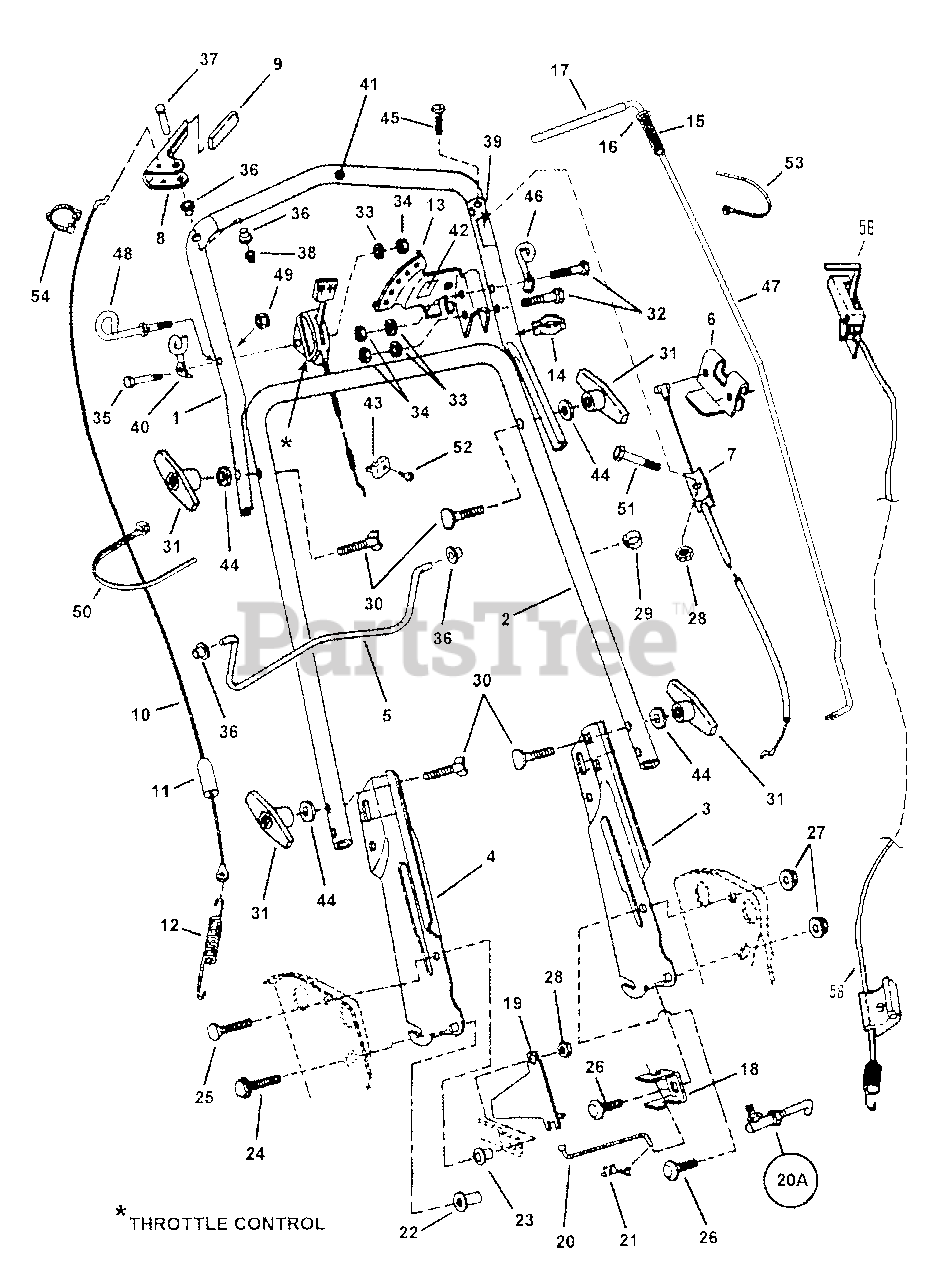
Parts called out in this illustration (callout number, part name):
1	HANDLE, Upper
2	HANDLE, Middle- 1990
3	HANDLE, Lower Left Hand
4	HANDLE, Lower Right Hand
5	BAIL, OPC Control (12.5" Wide)
6	CLIP, Blade Control
7	CABLE, Blade Control (49-1/4" long)
7	CABLE, Blade Control (46-15/16" long)
7	CABLE, Blade Control (49" long)
8	HANDLE, Wheel Drive
9	GRIP, Wheel Drive Handle
10	CABLE, Clutch Pull (Z-Bend, 38-5/8" long)
11	COVER, Vinyl
12	SPRING, Clutch
13	SECTOR, Speed
14	WIRE TIE, 1.29" Long (Black)
15	SPRING, Speed Control
16	WASHER, 3/8" Flat
17	GRIP, Speed Control Handle
18	ANCHOR, Speed Control
19	GUIDE, Lower V-Belt
20	ROD, Transfer
20A	ASSEMBLY, Transfer Rod
21	CLIP, Transfer Rod 1/4"
22	TEE-NUT, 5/16-18
23	BUSHING, Differential
24	BOLT, 5/16-18 x 3/4" Hex Flange Lock GR5
25	SCREW, 5/16-24 x 1" Hex Head Cap GR5
26	BOLT, 5/16-18 x 5/8" Short Neck Carriage GR5
27	NUT, 5/16-18 Hex Flange Lock GR5
28	NUT, 5/16-24 Hex Center Lock GR5
29	CLIP, Cable/Wiring
30	SCREW, 5/16-18 x 1-7/8" Curved Head GR2
31	T-KNOB, 5/16-18 (BLACK)
32	SCREW, 1/4-20 x 1-1/2 Hex Head Cap GR5
33	WASHER, 1/4" Internal Tooth Lock
34	NUT, 1/4-20 Hex GR5 or B
35	SCREW, 1/4-20 x 2" Hex Head Cap GR5
36	BUSHING
37	PIN, 1/4" x 1-1/2" (for clutch handle)
38	PUSH-NUT, 1/4" (for handle pin)
39	DECAL, Blade Control (Left Hand Side)
39	DECAL, Handle International Warning
40	GUIDE, Rope
41	FOAM GRIP, .84 I.D. x 12" long
42	DECAL, Speed Select
42	DECAL, Speed Select (Euro)
43	CLAMP, Casing
44	WASHER, 5/16" Internal Tooth Lock
45	SCREW, 5/16-24 x 1-1/2" Round Hd. Machine, GR5
46	GUIDE, Rope
47	LEVER, Speed Control
48	GUIDE, Rope
49	NUT, 1/4-20 Hex GR5 or B
50	CABLE-TIE, 7"
51	SCREW, 1/4-20 x 1-1/2" Hex Head Cap, GR5
52	SCREW, #10-32 x 5/8" Hex Head Self-Tap
53	WIRE TIE, 11" Long (Black)
54	CLAMP, 7/8" Double Cable
56	CONTROL, Swivel Wheel Lock Cable 56.5"
